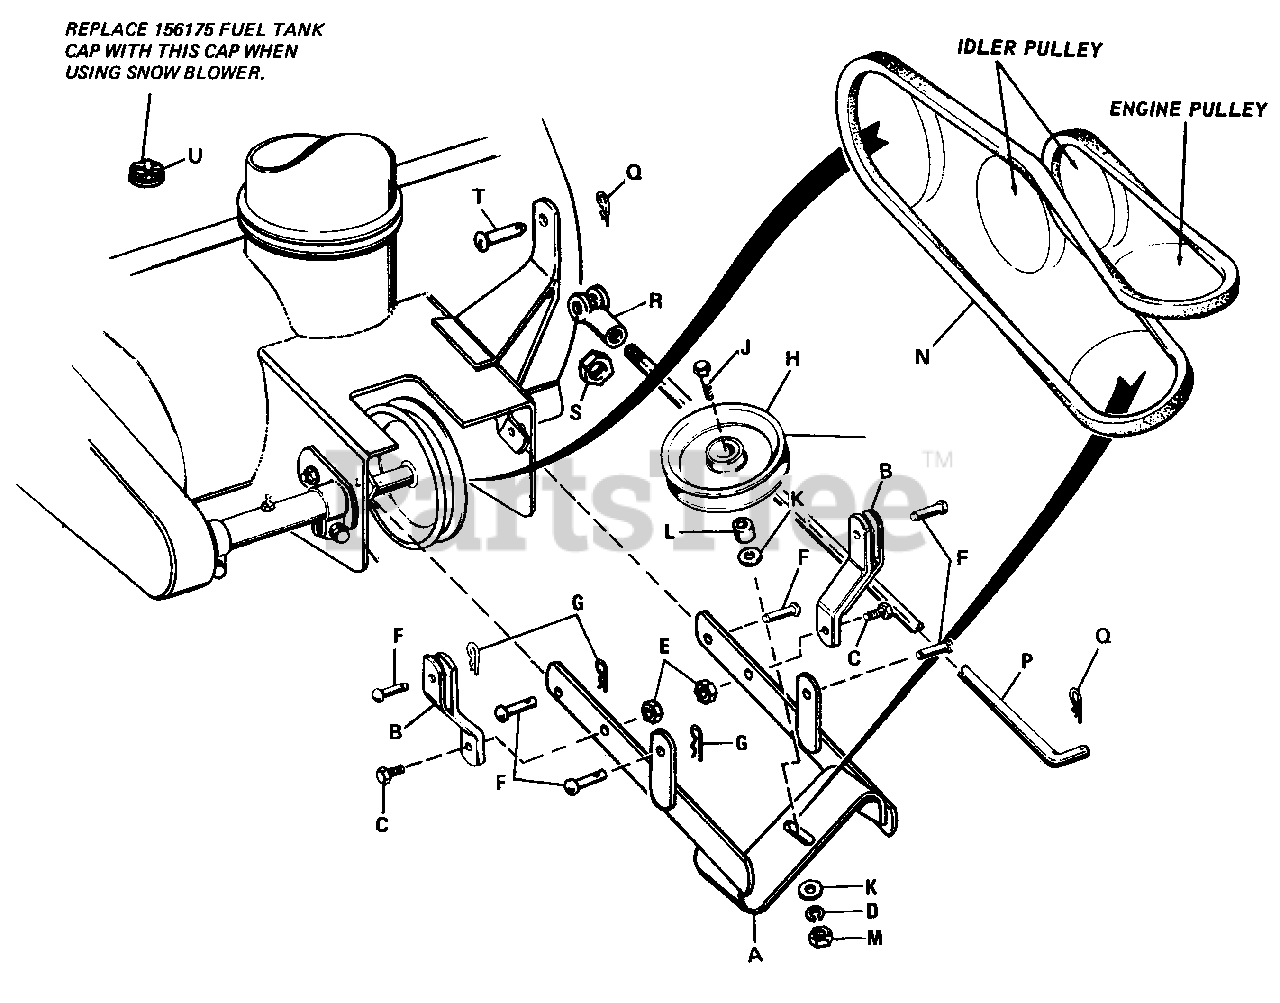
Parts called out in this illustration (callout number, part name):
A	Hitch Assembly
B	Support Arm Assembly
C	Hex Capscrew, 3/8"-16 x 1" lg.
D	Lock Washer, 3/8"
E	Hex. Nut, Full Lock, 3/8"-16
G	Spring Clip
J	Hex. Capscrew, 3/8"-16 x 1-3/4" lg.
K	Plain Washer, 3/8"
M	Hex. Nut, Full, 3/8"-16
N	"V" Belt
P	Front Lift Rod
Q	Spring Clip
R	Adj. Yoke
S	Hex. Nut, Full, 1/2"-20
U	Cap (Winter) Fuel Tank
